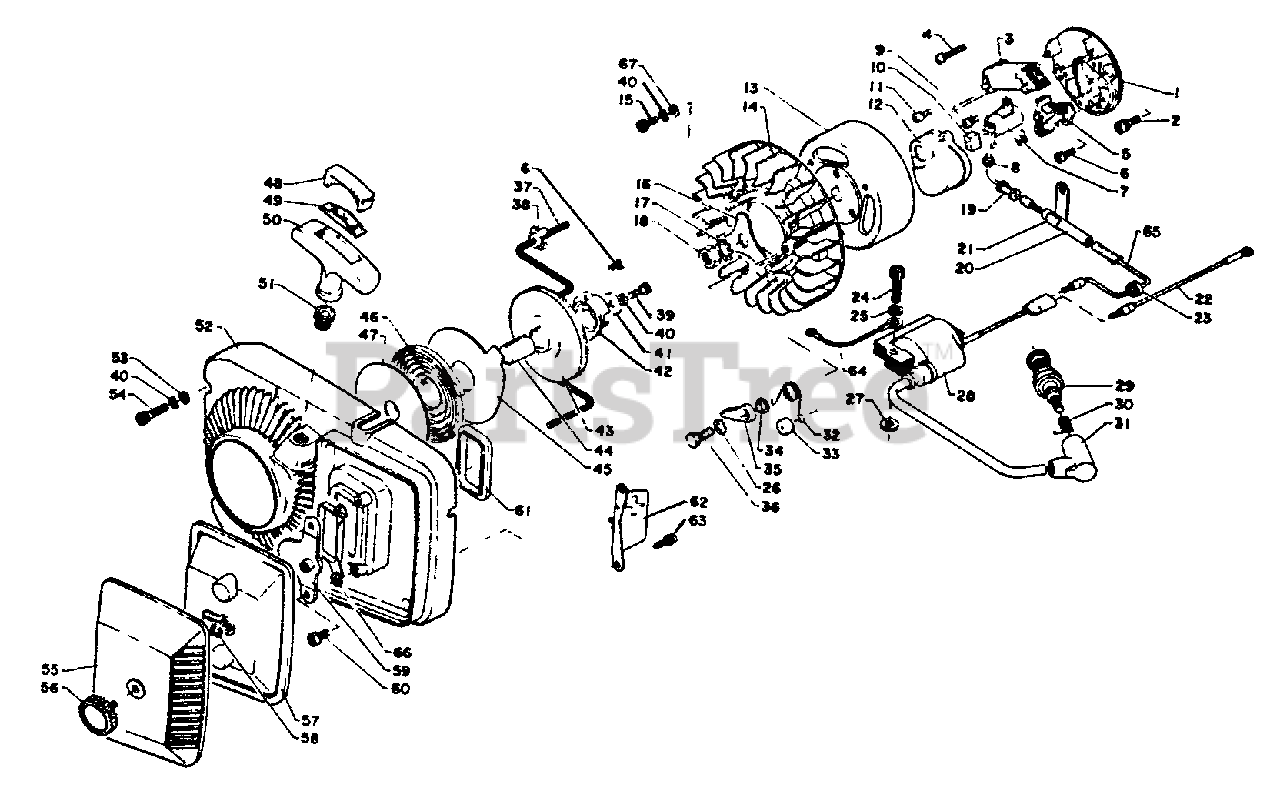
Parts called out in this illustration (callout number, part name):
1	PLATE, STATOR
2	SCREW - 5X18
3	Primary ignition coil
4	SCREW - 4X25
5	CONTACT POINT SET
6	SCREW - 4X10
7	CONDENSER 1
8	Rubber bushing
9	SCREW - 4X10
10	Oiler (0.1 felt)
11	SCREW - 4X12
12	COVER, BREAKER
13	FLYWHEEL
14	FAN
15	SCREW - 5X12
16	WASHER
17	WASHER - 10
19	Rubber bushing
20	Cover tube
21	CLIP
22	LEAD - GROUND
23	GROMMET
24	SCREW - 5X25
25	LOCKWASHER - 6
26	WASHER - 6
27	WASHER - 6
28	COIL, IGNITION
29	SPARK PLUG -- BPM-7A
30	TERMINAL, SPARK PLUG CAP
31	CAP, SPARK PLUG
32	SPRING, RETURN
34	SPACER
35	PAWL, STARTER
36	BOLT - 6X14
37	ROPE, STARTER
38	RETAINER, ROPE
39	SCREW - 5X15
40	LOCKWASHER - 5
42	CATCHER, PAWL
43	REEL, ROPE
45	PLATE, STARTER
46	SPRING, REWIND
47	PLATE, STARTER
48	CAP
49	RING, RETAINING
50	GRIP, STARTER
51	GUIDE, ROPE
52	CASE, STARTER
53	WASHER - 5
54	SCREW - 5X20
55	COVER, AIR FILTER
56	THUMBSCREW
57	FILTER, AIR
58	RING, RETAINING - 4
59	PLATE, PREVENT
60	SCREW - 5X10
61	O-RING
62	GUIDE, AIR
63	SCREW - 4X12
64	LEAD - GROUND
65	LEAD - GROUND
66	Seal packing holder
67	WASHER - 5
